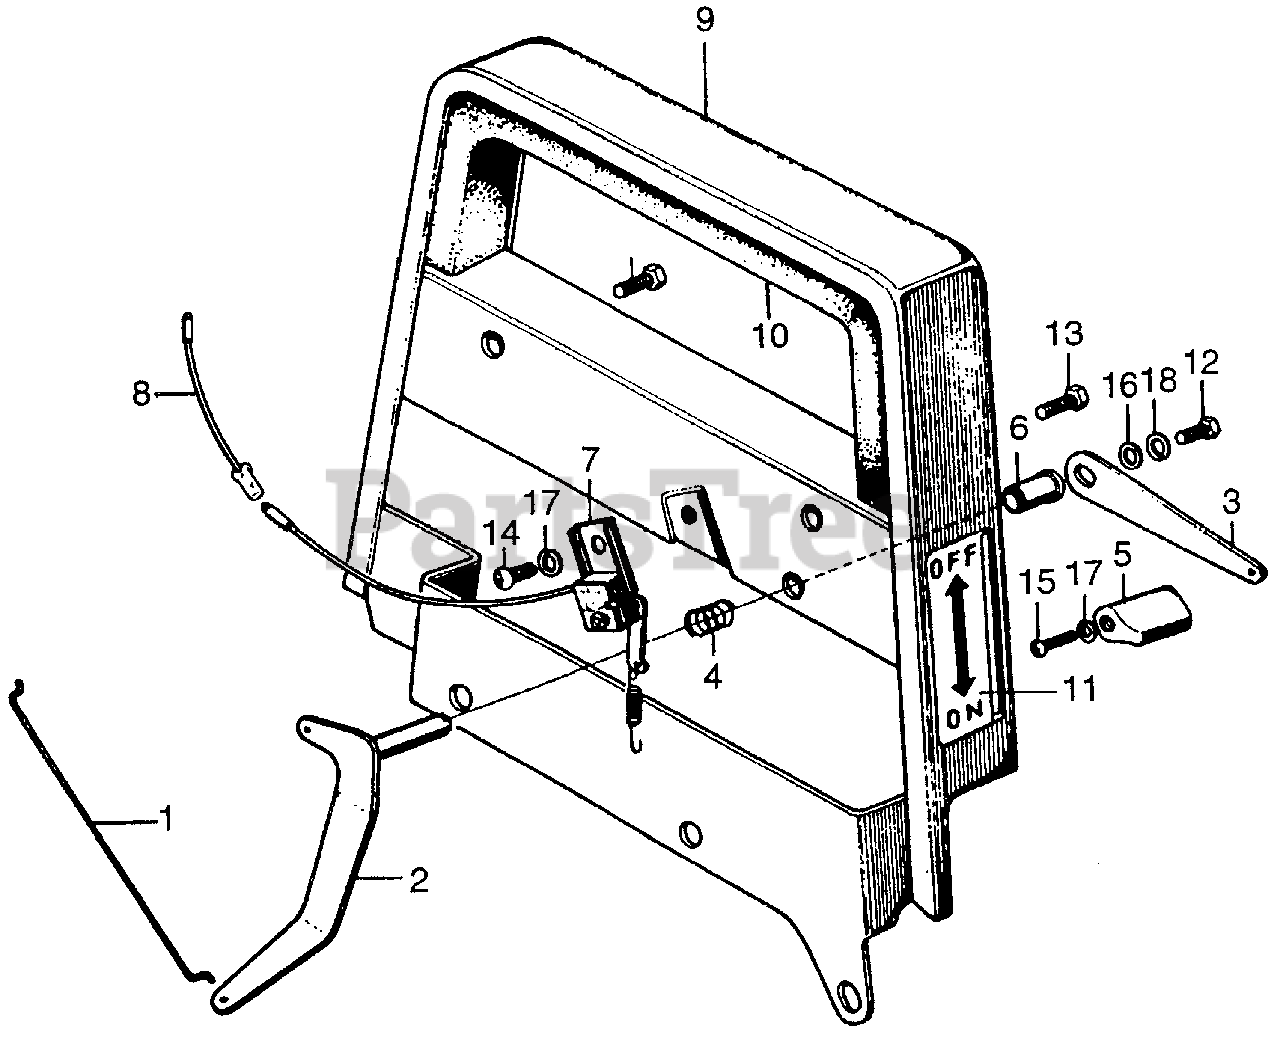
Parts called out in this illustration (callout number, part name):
1	ROD, LEVER (NOT AVAILABLE)
2	ARM, ON-OFF (NOT AVAILABLE)
3	LEVER, ON-OFF
4	SPRING, ON-OFF (NOT AVAILABLE)
5	KNOB, ON-OFF (NOT AVAILABLE)
6	BUSH, ON-OFF SHAFT
7	SWITCH ASSY., ENGINE
8	WIRE, SWITCH
9	HANDLE, CARRY
10	GRIP, CARRY HANDLE
11	PLATE, ON-OFF
12	BOLT, HEX. (5X12)
13	BOLT, HEX. (6X12)
14	SCREW, PAN (3X6) (NOT AVAILABLE)
15	SCREW, PAN (3X8)
16	WASHER, PLAIN (5MM)
17	WASHER, SPRING (3MM)
18	WASHER, SPRING (5MM)
